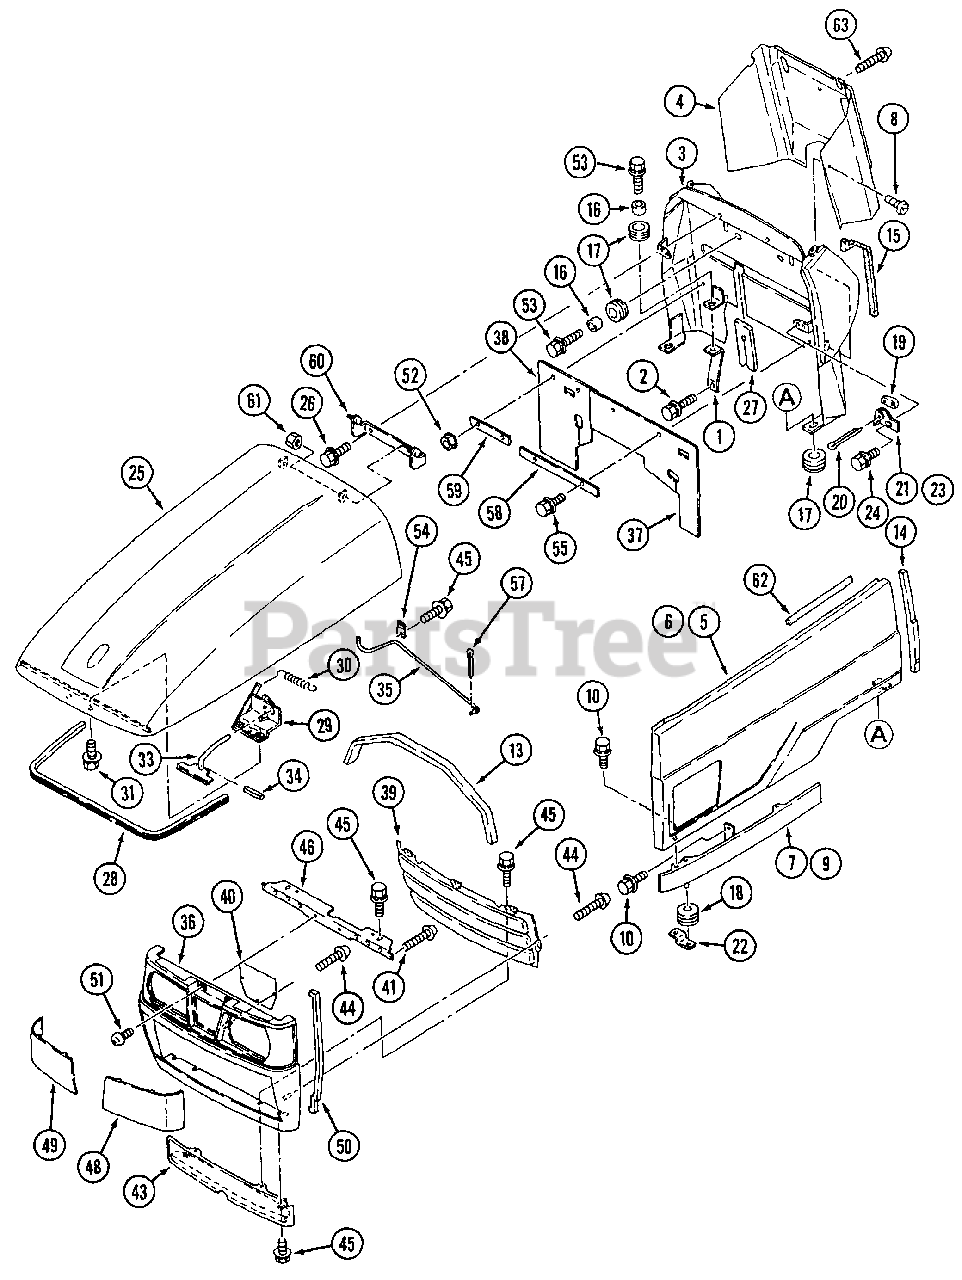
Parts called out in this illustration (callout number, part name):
4	Cover, Panel Rear
5	Cover, Side L.H.
6	Cover, Side R.H.
7	Cover, Side L.H.
9	Cover, Side R.H.
15	Seal, Foam
19	Hook
29	Bracket, Lever
39	Screen
40	Screen
41	Screw, Tapping
46	Support, Grille
48	Cover, Lamp L
49	Cover, Lamp R
57	Pin
60	Bracket, Hood
62	Rubber, Cushion
